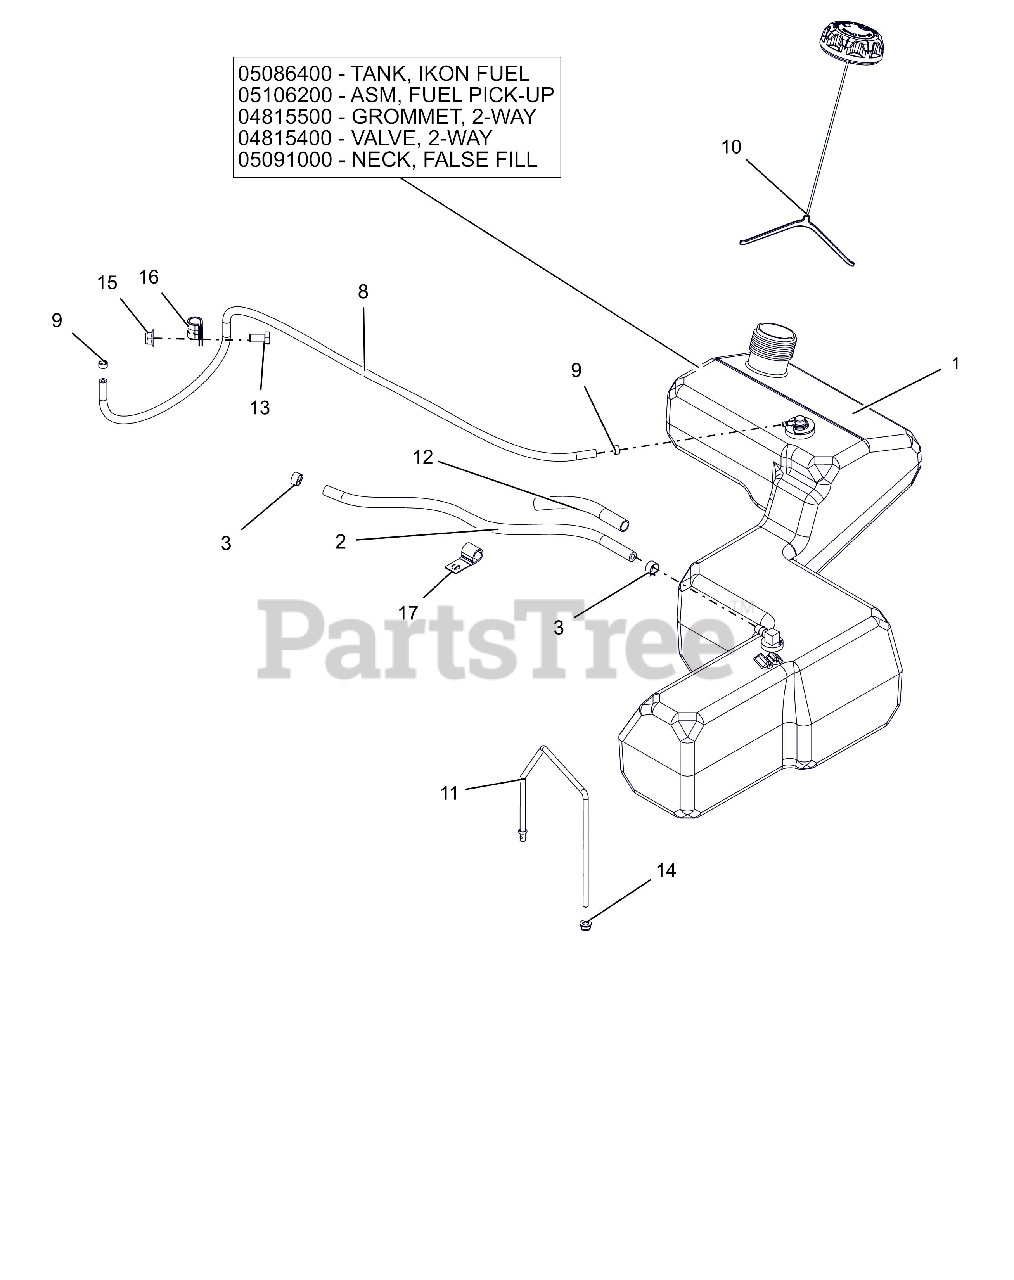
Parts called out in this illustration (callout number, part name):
1	ASSEMBLY, FUEL TANK IKON(2017)
1	TANK, IKON FUEL (2017)
1	ASM, IKON FUEL PICK-UP
1	GROMMET, 2-WAY
1	VALVE, 2-WAY
1	NECK, FALSE FILL-2017 IKON
2	HOSE, .25 LOW-PERM BULK GAS
3	CLAMP, FUEL LINE
8	HOSE, .188 LOW-PERM BULK GAS
9	CLAMP-HOSE, SPRING .188
10	CAP, FUEL VENT-IN 2.25" RATCH.
11	BRKT, FUEL TANK HOLD DOWN
12	WRAP, ANTIABRASION .5X.064WALL
13	@BLT-HEX .38-16X.75 GR5 YWZC
14	@NUT-LK-NYL-FLG .25-20 YWZC
15	@NUT-LK-NYL-FLG .38-16 YWZC
16	CLAMP, CUSHIONED STEEL
17	J-CLAMP
